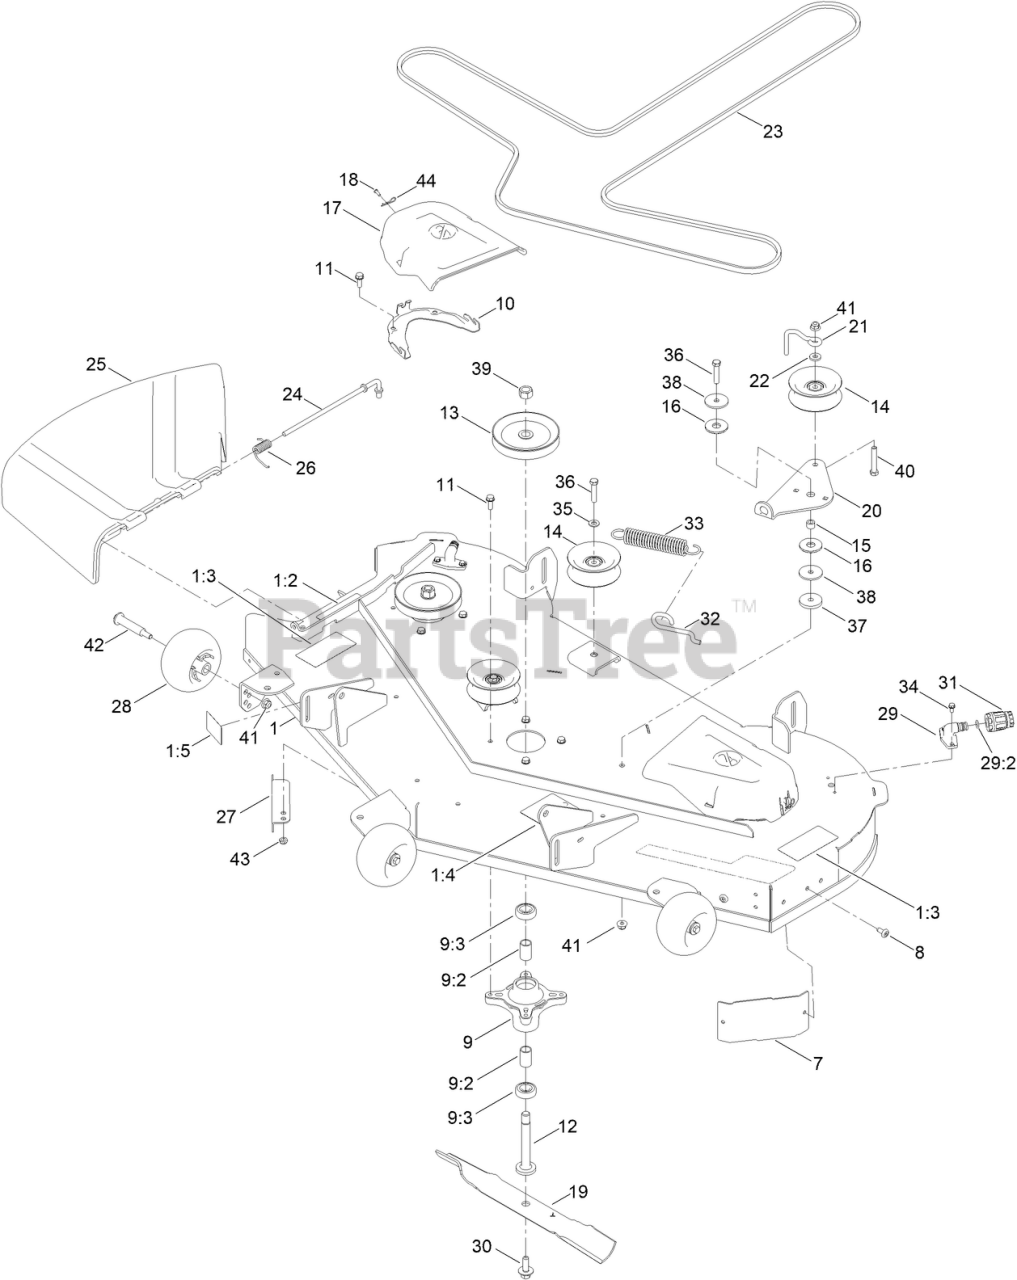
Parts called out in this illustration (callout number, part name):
1	54 IN DECK DECAL ASM
1:2	DECAL-DANGER
1:3	DECAL-DANGER, DECK
1:4	DECAL-ROUTING, BELT
1:5	DECAL-SCALP, ANTI
7	BAFFLE-CORNER
9	SPINDLE ASM
9:2	SPACER
9:3	BEARING-BALL
10	BRACKET-COVER, BELT
11	SCREW-TAPTITE
12	SHAFT-SPINDLE
13	PULLEY ASM
14	PULLEY-IDLER, FLAT
15	SPACER
16	WASHER-FRICTION, COMPOSITE
17	COVER-BELT
18	SCREW
19	BLADE-HI LIFT
20	ARM-IDLER
21	BELT GUIDE - IDLER
22	SPACER-HUB, BLOWER
23	BELT-V (A SEC, 145.5 EL)
24	ROD-PIVOT
25	DEFLECTOR-DISCHARGE
26	SPRING-TORSION
27	BAFFLE-CUTOFF
28	ROLLER-SCALP, ANTI
29	FITTING-WASHOUT
29:2	O-RING
30	BOLT-BLADE, SEMS
31	CONNECTOR-HOSE
32	HOOK-RETURN SPRING
33	SPRING-EXTENSION
34	SCREW-HWH
35	WASHER-FLAT
36	SCREW-HH
37	WASHER-PLAIN
38	WASHER-REBOUND
39	NUT-HEX
40	SCREW-HH
41	NUT-HF, NI
42	BOLT-SHOULDER
44	PIN-HAIR
